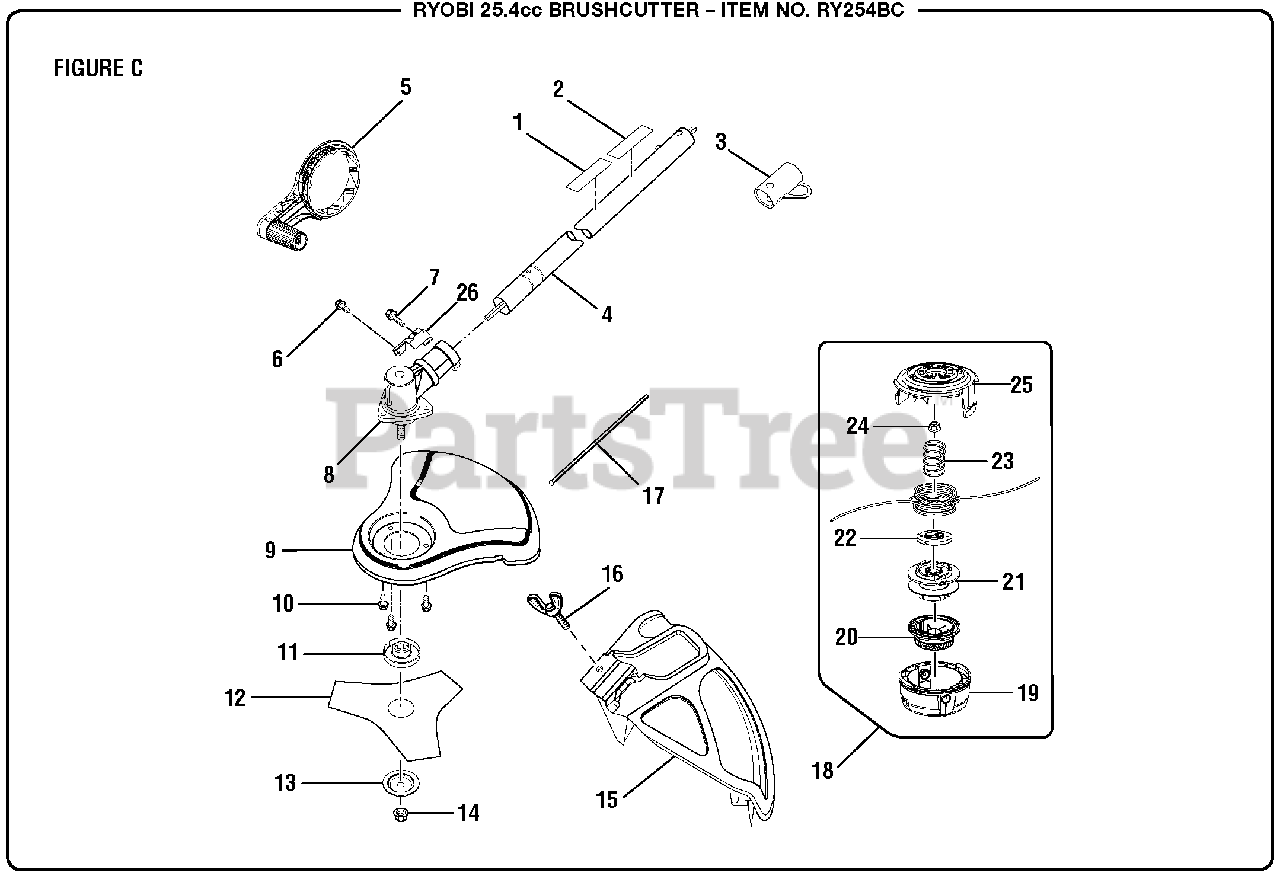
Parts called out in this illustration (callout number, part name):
1	Expand-It Logo Label
2	Brushcutter Safety Label
3	Storage Hanger Cap
4	Lower Straight Shaft Boom Assembly
5	Crank Handle Assembly
6	Screw (1/4-20 x 1-1/4 in., Hex Washer Hd. S.T.)
7	Screw (10-24 x 5/8 in., Hex Washer Hd. S.T.)
8	Gear Case Assembly
9	Brushcutter Guard
10	Screw w/Washer (10-24 x 1/2 in., Slotted Hex Hd.)
11	Flanged Washer
13	Cupped Washer
14	Lock Nut (M8 x 1.25 in., Left Hand Threads)
15	Grass Deflector Assembly
16	Screw (1/4-20 x 7/8 in.)
17	Gear Head Locking Tool
18	Trimmer Head Assembly (.095)
19	Lower Housing
20	Bump Knob (Green)
22	String Guide
23	Compression Spring
24	Hex Nut (M8, L.H. Thread)
25	Upper Housing
26	String Guard Clamp
